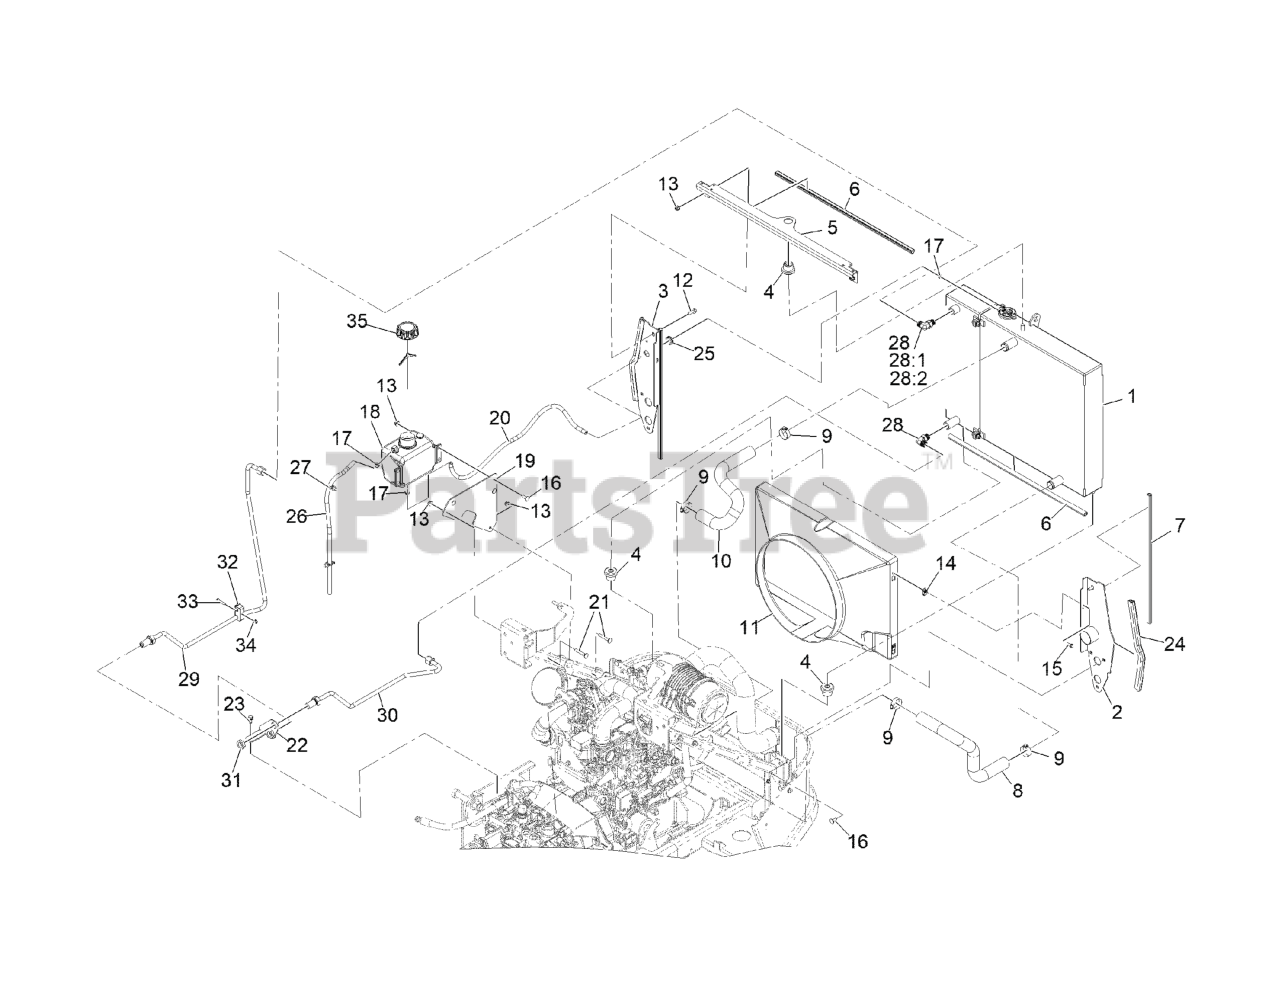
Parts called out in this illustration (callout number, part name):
1	COOLING ASM
2	SUPPORT-RADIATOR, LH
3	SUPPORT-RADIATOR, RH
4	MOUNT-ISOLATOR
5	BRACKET-COOLING, TOP
6	SEAL-BULB
7	SEAL-BULB
8	HOSE-RADIATOR, LOWER
9	CLAMP-HOSE
10	HOSE-RADIATOR, UPPER
11	SHROUD-FAN
12	SCREW-HHF
13	NUT-HF, NI
15	SCREW-HWH
16	SCREW-CARR
17	CLAMP-HOSE
18	TANK-OVERFLOW, W/CAP
19	BRACKET-BOTTLE
20	HOSE-FUEL
21	BOLT-CARR
22	BRACKET-BULKHEAD
23	Screw-HWH 5/16-18 X 3/4 Tf
24	SEAL-BULB
25	GROMMET
26	HOSE-FUEL
27	CLIP-TIE
28	FITTING-ELBOW, 90 DEG
28:1	O-RING
28:2	O-RING
29	HYDRAULIC TUBE ASM
30	HYDRAULIC TUBE ASM
31	NUT-BULKHEAD
32	CLAMP-TWIN
33	SCREW-HH
35	CAP-W/TETHER
